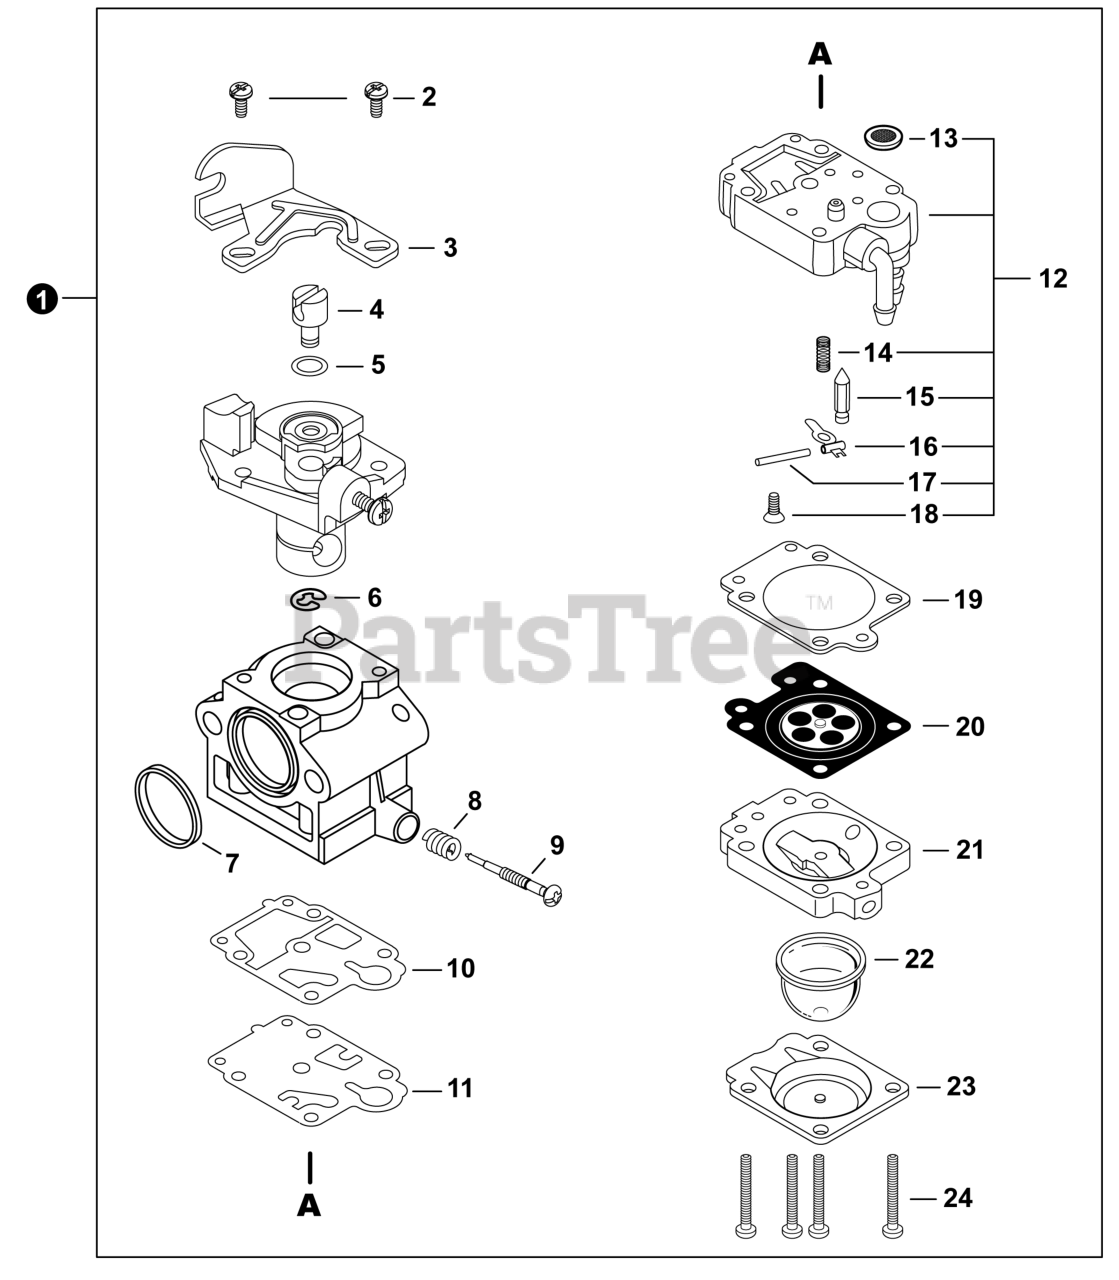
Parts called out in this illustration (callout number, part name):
1	CARBURETOR HR02-2B01-0000
3	BRACKET, CABLE
7	RING, PACKING
9	NEEDLE - MIXTURE
10	GASKET, PUMP
11	DIAPHRAGM, PUMP
12	BODY ASSY, PUMP
13	SCREEN, FUEL INLET
14	SPRING, METERING LEVER
15	VALVE, INLET NEEDLE
16	LEVER, METERING
17	PIN, METERING LEVER
19	GASKET, METERING DIAPHRAGM
20	DIAPHRAGM, METERING
21	BODY ASSY, PURGE
22	BULB, PURGE
23	RETAINER, PURGE BULB
